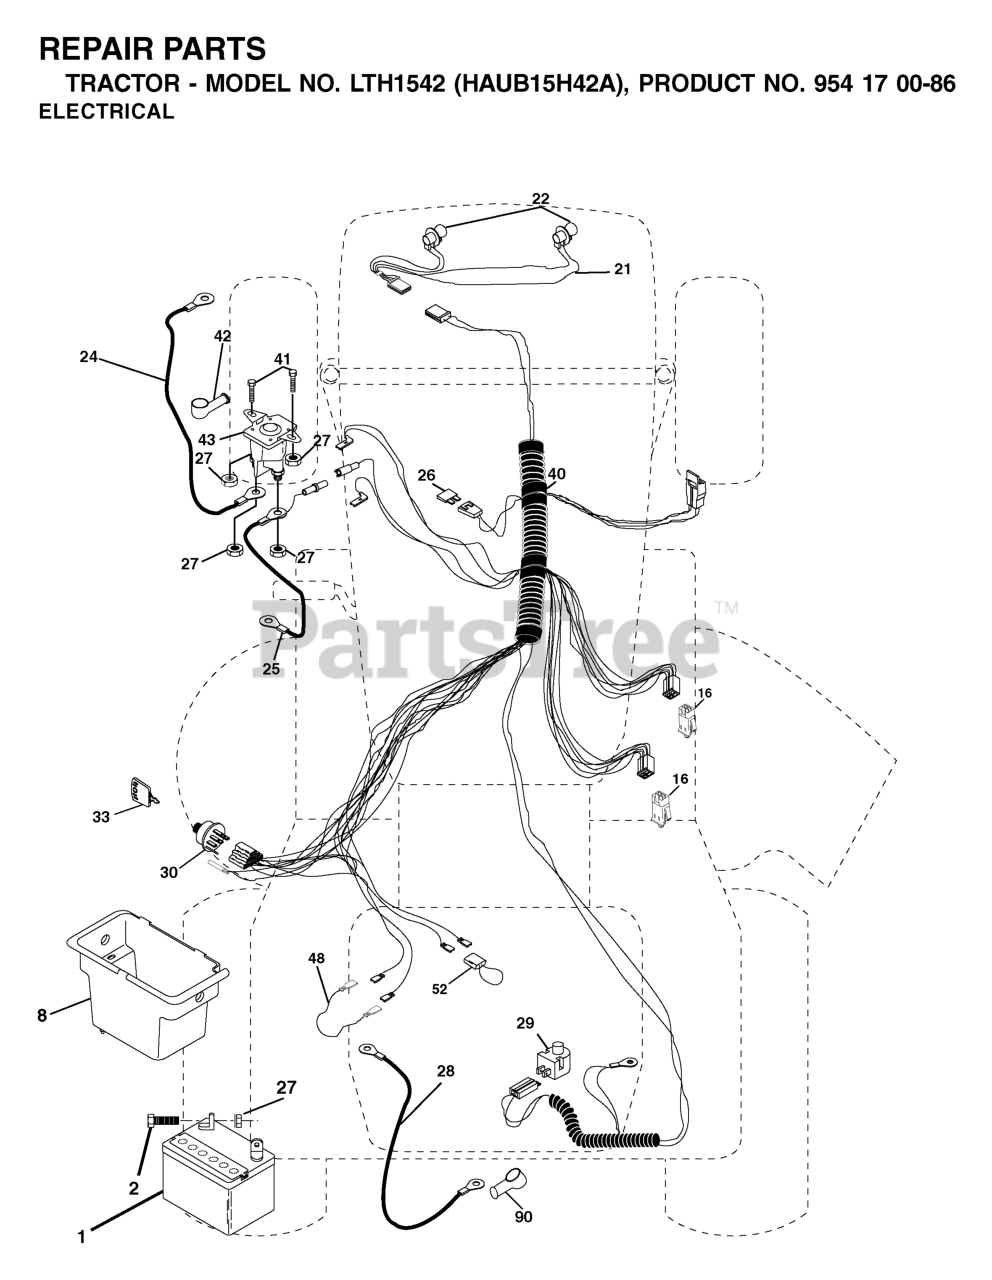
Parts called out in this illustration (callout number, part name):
1	Battery 12 Volt 25 Amp
2	BOLT.HEX.1/4.X.3/4.DICHROMATE
8	BOX.BATTERY.FENDER
16	SWITCH INTERLOOK PUSH-IN
21	HARNESS.ASM.LIGHT WSL
24	BATTERY CABLE GT
25	CABLE BATTERY
26	FUSE 20AMP
27	NUT
28	CABLE T
29	RP.SWITCH.PLUNGER.NC.GRAY
30	IGNITION SWITCH
33	KEY MLD GEN DELTA
40	HARNESS.IGNITION
41	BOLT
42	TERMINAL COVER
43	SOLENOID
48	ADAPTER.AMMETER
52	WIRE PROTECTION LOOP
90	COVER TERMINAL
